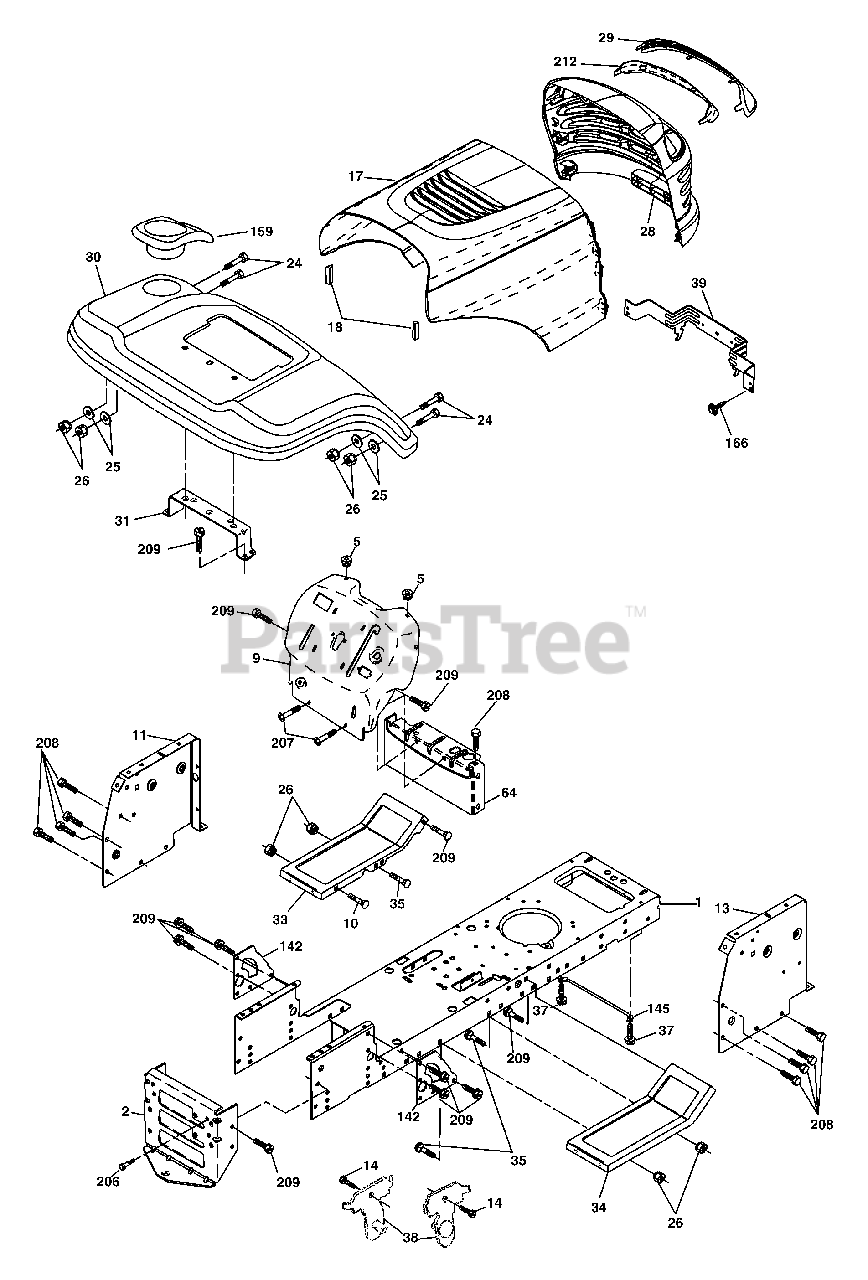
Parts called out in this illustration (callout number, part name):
1	Chassis
2	Drawbar
5	Bumper Hood/Dash
9	Dash P/L
10	Bolt Carriage 3/8-16 x 1
11	Panel Dash Lh
14	Screw Thdrol 3/8-16 x 1/2
17	Hood
18	Bumper Hood
24	Bolt Fin Hex 3/8-16 unc x 1 Gr. 5
26	Nut Lock Hex W/Ins 3/8-16 unc
28	Grille/Lens Asm
29	Lens Grille
31	Bracket Fender
33	Footrest LH
34	Footrest RH
35	Bolt RDHD SHT SQNK 3/8-16 x 3/4
37	Screw Thdrol 6/16-18 x 1/2 TYT
38	Bracket Asm Pivot Mower Rear
39	Bracket Pivot
58	Duct Air
64	Dash Lower STLT
142	Plate Reinforcement STLT
145	Rod Pivot Chassis/Hood
159	Cupholder
166	Screw Hwhd Hi-Lo #13-16 x 3/4
206	Bolt Shoulder 5/16-18
208	Screw Thdrol 3/8-16 x 1/2
209	Screw Hexwsh Thdr 3/8-16 x 3/4
212	Insert Grille Reflective
